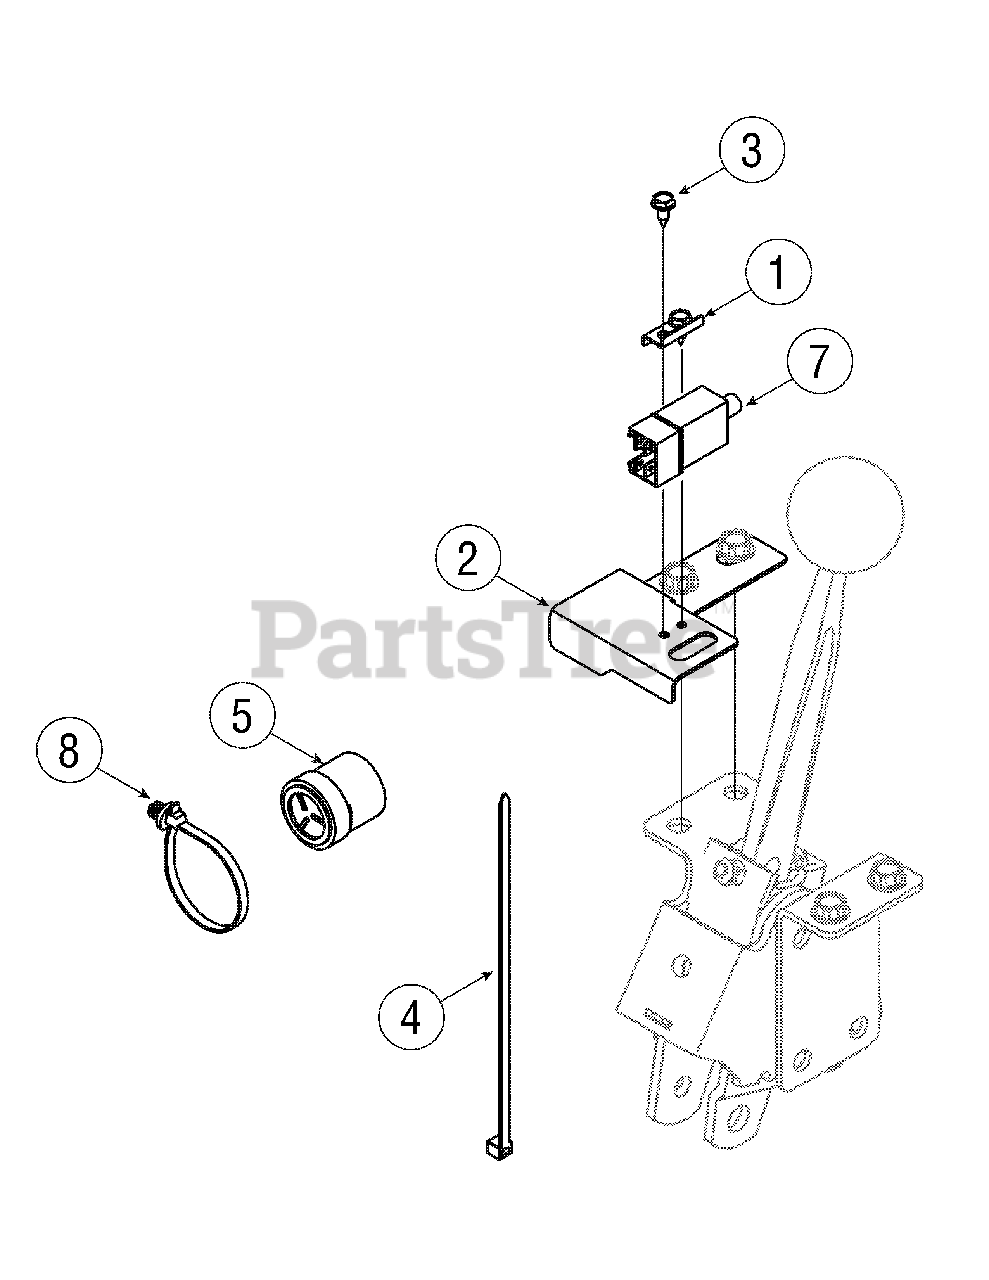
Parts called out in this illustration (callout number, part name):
1	Plate, Switch
2	Bracket, Switch
3	Scr., AB, #10-16 x .500
4	Tie, Cable, 3/16 x .05 x 7.4
5	Cont., Acsry., Reverse
7	Switch, Plunger (Double Pole)
8	Tie, Cable, 19 x 8.39", Tree Mnt.
